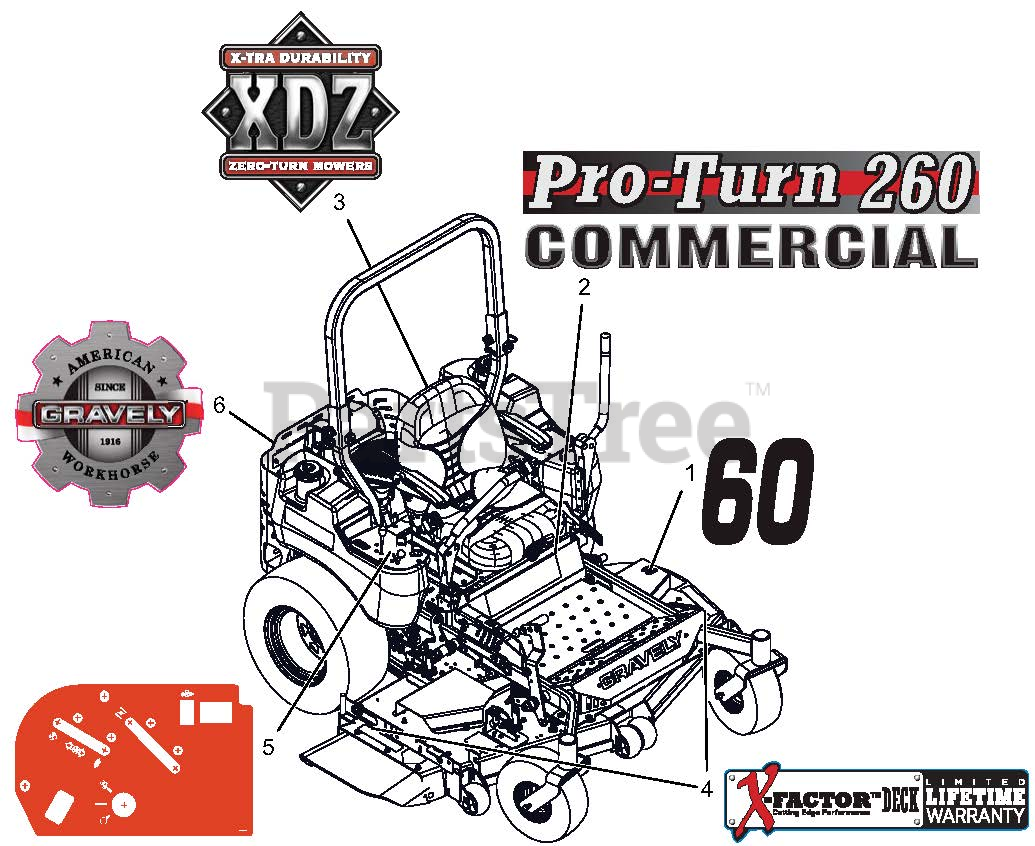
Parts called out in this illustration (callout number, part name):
1	DECAL, 60"
2	DECAL, PROTURN 260
3	DECAL, XDZ
4	DECAL, X-FACTOR DECK
5	DECAL, CONTROL PANEL NON-EFI
6	DECAL, GRAVELY HERITAGE-LARGE
